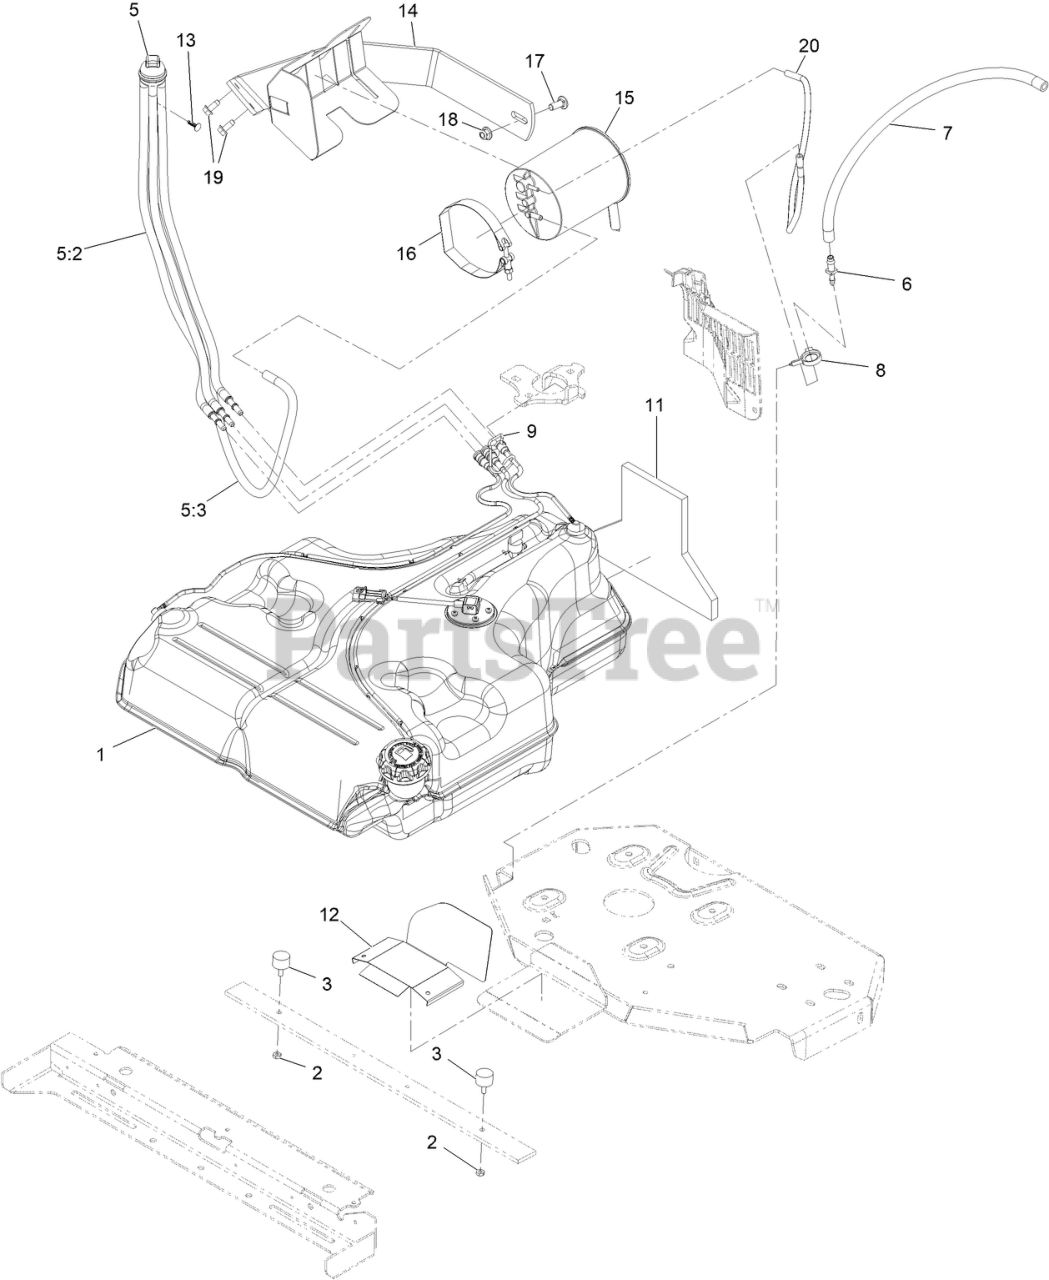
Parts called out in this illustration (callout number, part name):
1	FUEL TANK ASM
2	NUT-JAM
5	FUEL MANIFOLD VENT ASM
5:2	HOSE-FUEL
5:3	HOSE-FUEL
6	FITTING-STRAIGHT
7	HOSE-FUEL
8	CLAMP-HOSE
9	RETAINER-LINE, VAPOR
11	INSULATION-FOAM, FUEL TANK
12	GUARD-EXHAUST
13	PLUG-PLASTIC
14	MOUNT-CANISTER
15	CANISTER-CARBON, 1200CC
16	CLAMP, T-BOLT
17	SCREW-CARR
18	NUT-HF, NI
19	Screw-HWH 5/16-18 X 3/4 Tf
20	Hose-Vent, Formed
